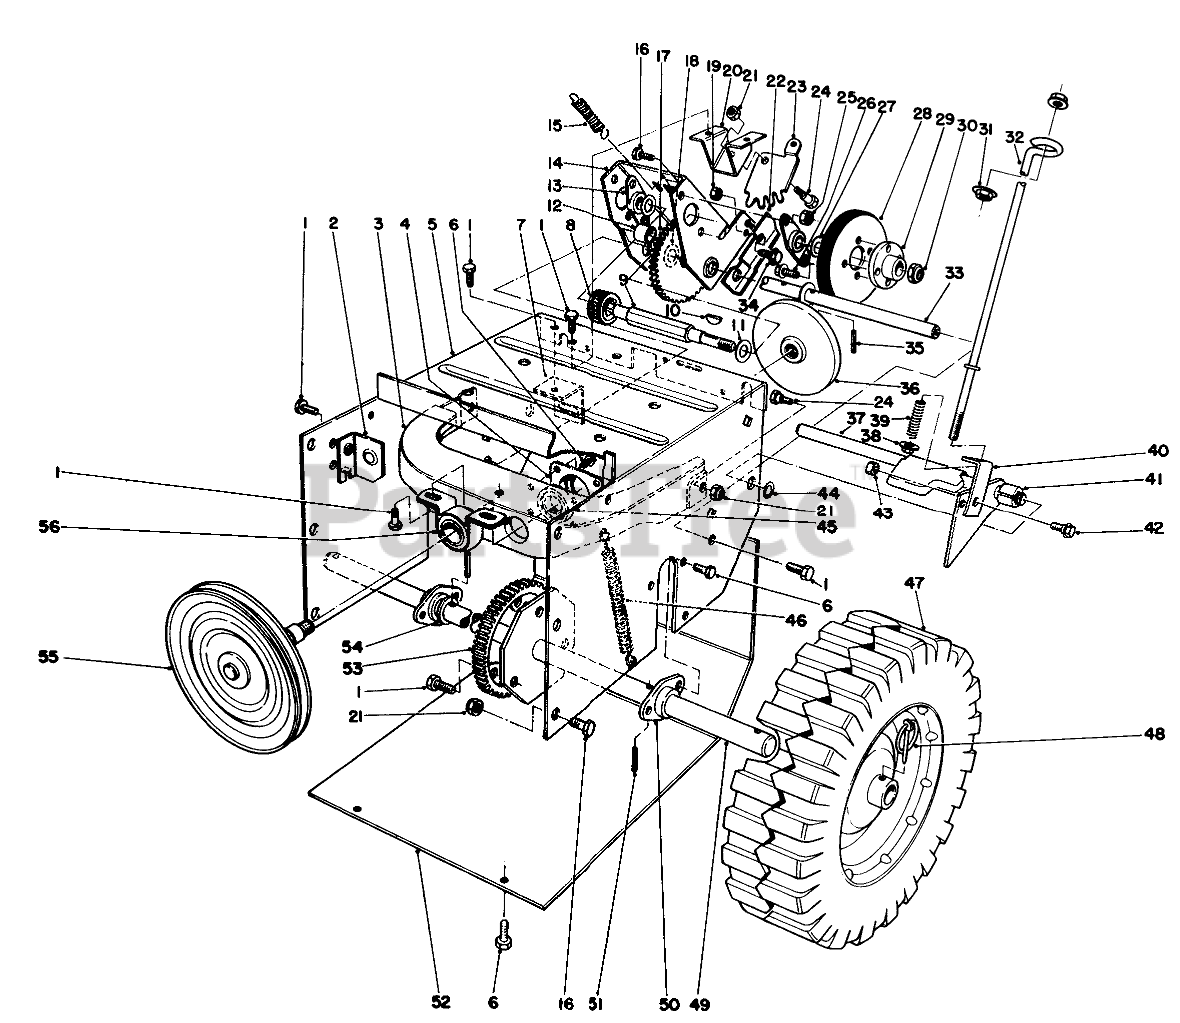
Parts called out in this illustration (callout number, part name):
1	SCREW-HWHTF
2	AUGER CLUTCH MTG FRT
3	"OBS" FRICTION PLT FRAME
4	CUP-BEARING
5	Frame-Traction
6	SCREW-HWH
7	BRACKET-MOUNT, REAR
8	PINION
9	SHAFT-WHEEL, FRICTION
10	KEY-WOODRUFF
11	WASHER-FLAT
12	5/8ID X 1LG BUSHING
13	BEARING-WHEEL, FRICTION
14	BRACKET-SLIDING
15	SPRING-TRACTION
16	SCREW-HH
17	Intermediate Gear & Bushing (Incl. Ref. #12)
18	WASHER-SPECIAL
19	NUT-LOCK, NI
20	MOUNT-LEVER
21	NUT-LOCK, NI
22	CAM-RECEIVER
23	GEAR-QUADRANT
24	BOLT-SHOULDER
25	NUT-LOCK, CONE
26	SCREW-HWHTF
27	WASHER-THRUST
28	WHEEL-FRICTION
29	HUB-WHEEL, FRICTION
30	NUT-LOCK, NI
31	NUT-HF
32	ROD-TRACTION, LOWER
33	SHAFT-PIVOT
34	Screw
35	PIN-SPRING
36	PLATE-FRICTION
37	Traction Engagement Asm.
38	NUT-HHF
39	SPRING
40	BRACKET-TRACTION
41	SPACER
42	SCREW
43	NUT-LOCK, NI
44	RING-RETAINING
45	BEARING-BALL
46	SPRING-PLATE, FRICTION
47	Wheel
48	PIN-LYNCH
49	AXLE SHAFT WA
50	BEARING-AXLE
51	PIN-SPRING
52	Bottom Cover
53	GEAR-AXLE
54	WASHER-THRUST
55	Pulley & Shaft
56	BUSHING ASM
